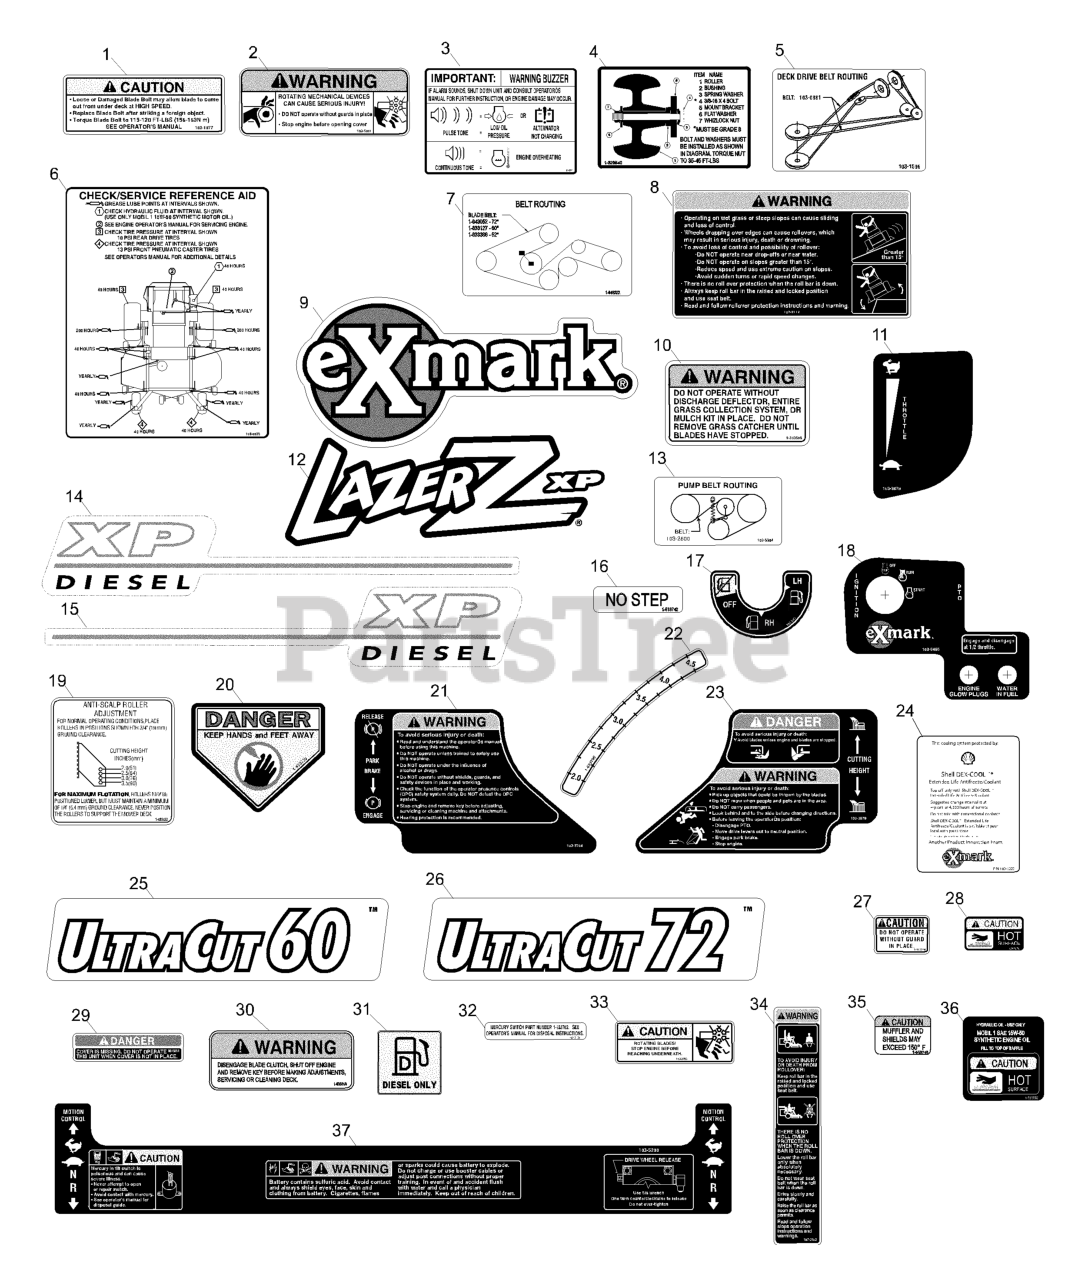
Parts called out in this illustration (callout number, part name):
1	DECAL,BOLT TORQUE
2	DECAL-DEVICES, ROTATING
3	DECAL-BUZZER, WARNING
4	DECAL,ROLLER MOUNTING
5	DECAL,BELT ROUTING XP
6	DECAL,CHECK/SERVICE XP
7	DECAL,BELT ROUTING
8	DECAL-WARNING
9	DECAL,EXMARK LOGO
10	DECAL-WARNING, DISCHARGE
15	DECAL,XP HOOD RH
16	DECAL,NO STEP
17	DECAL-VALVE, FUEL
18	DECAL,IGNITION/PTO XP
19	DECAL,ANTISCALP
20	DECAL-DANGER
21	DECAL,PARK BRAKE
22	DECAL-HEIGHT, DECK
23	DECAL,CUTTING HEIGHT
24	DECAL,SHELL COOLANT
25	DECAL,ULTRACUT 60
26	DECAL,ULTRACUT 72
27	DECAL-GUARD
28	DECAL-CAUTION
29	DECAL-COVER, MISSING
30	DECAL,WARNING
31	DECAL-FUEL
32	DECAL-SWITCH, MERCURY
33	DECAL-FAN, RADIATOR
34	DECAL-WARNING, FOLDING RO
37	DECAL,CONSOLE TOP
